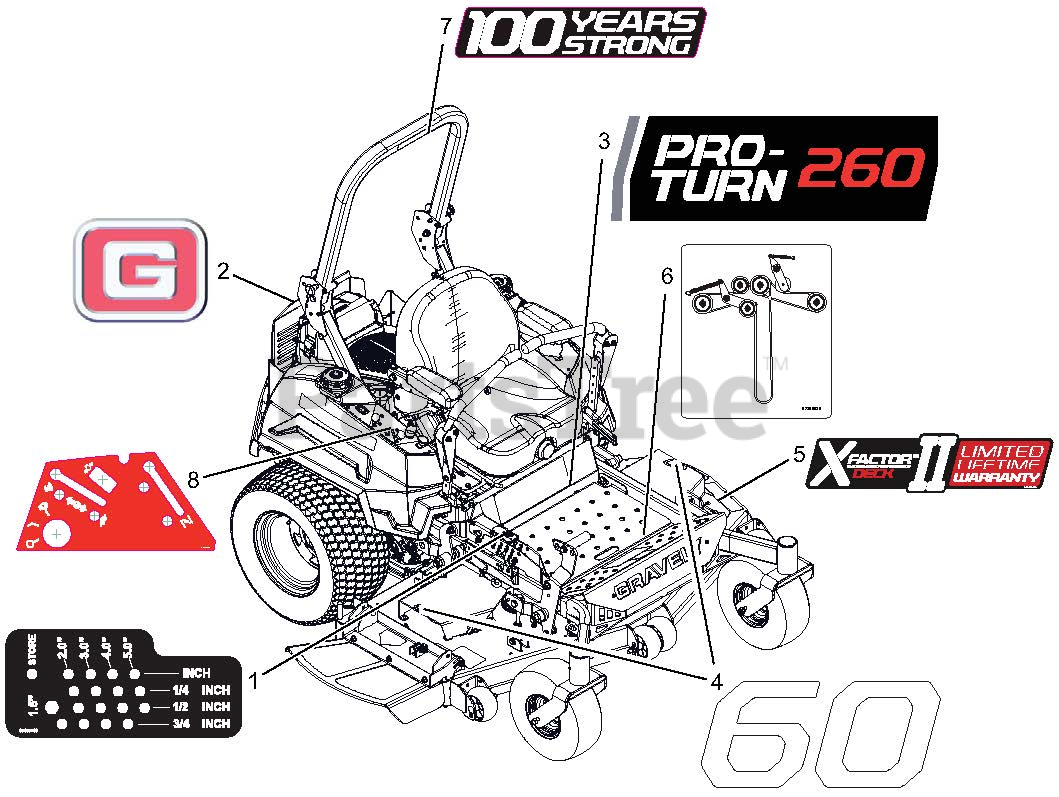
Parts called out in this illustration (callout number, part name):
1	DECAL, HEIGHT OF CUT
2	DECAL, GRAVELY BRAND
3	DECAL, PRO-TURN 260
4	DECAL, 60"
5	DECAL, X-FACTOR DECK
6	DECAL, BELT ROUTE RH BK SIDE IDLER
7	DECAL, GRAVELY 100 YEAR
8	DECAL, NON-EFI CONTROL PANEL
